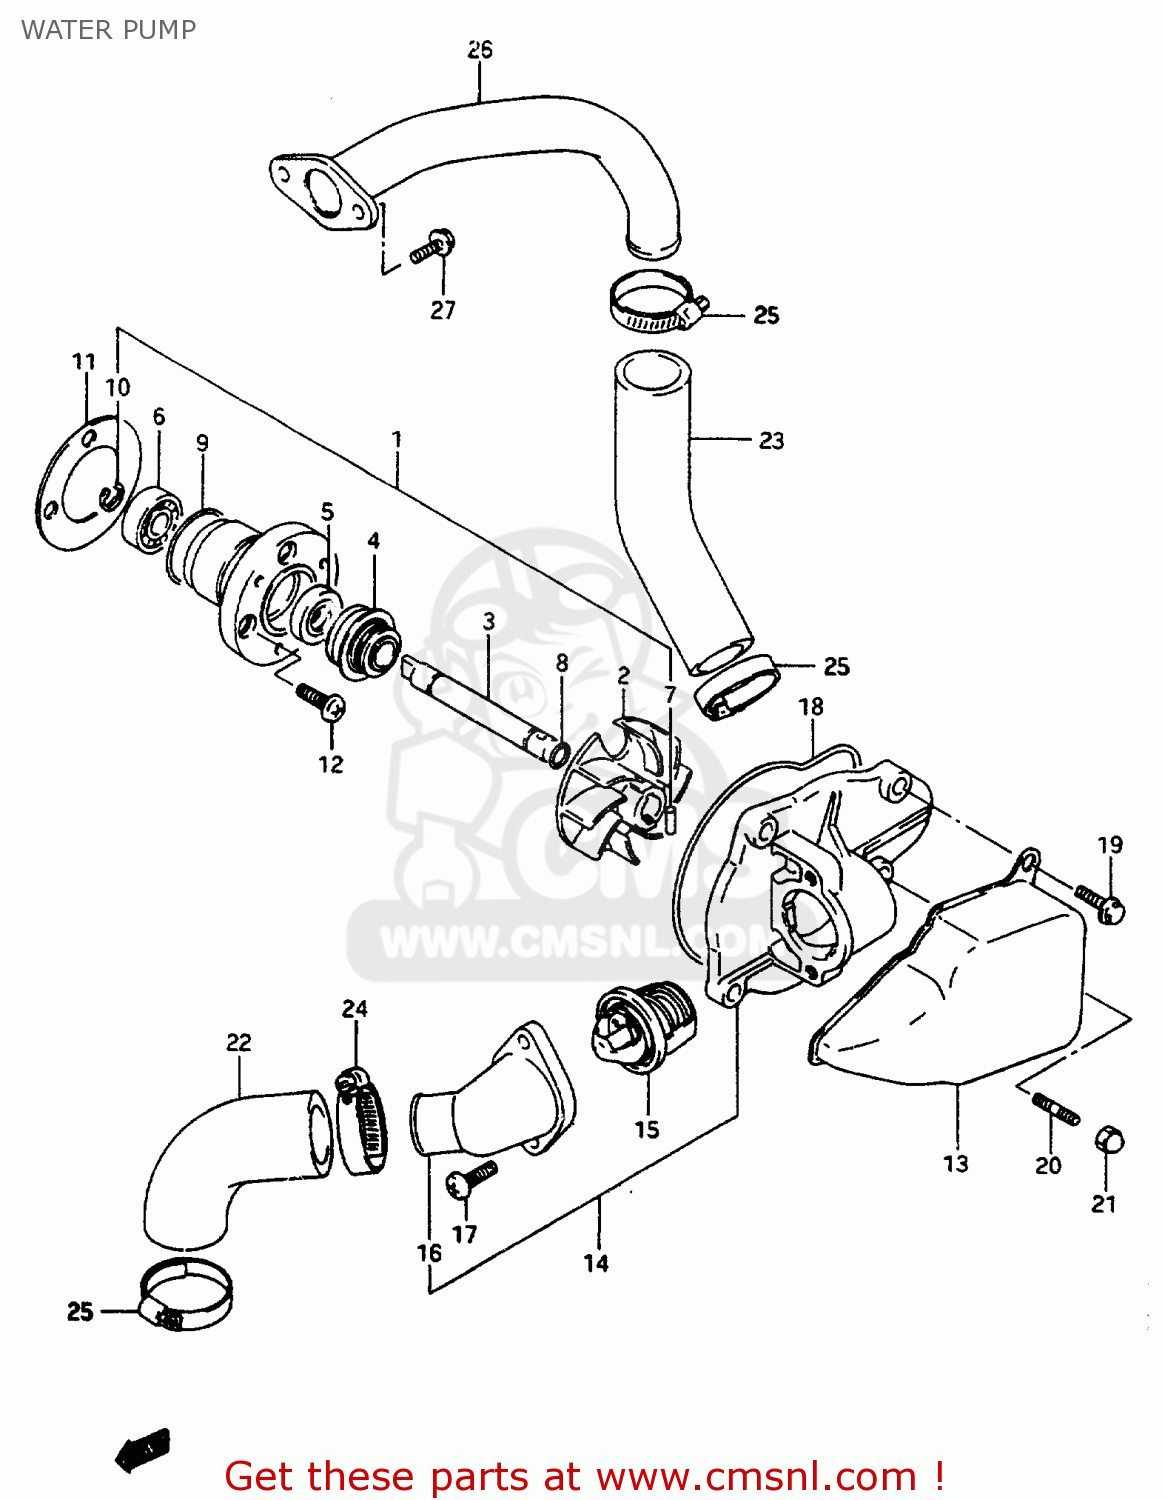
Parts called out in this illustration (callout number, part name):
1	PUMP ASSEMBLY,WATER
2	IMPELLER
3	SHAFT
4	SEAL,MECHANICAL
5	OILSEAL
6	BEARING,10X26X8
7	PIN
8	O RING
9	O RING
10	E RING
11	GASKET,WATER PUMP (NAS)
12	SCREW
13	COVER,WATER PUMP
14	CASE ASSY,WATER PUMP
15	THERMOSTAT,WATER
16	CONNECTOR
17	SCREW
18	O RING,WATER PUMP CAP
19	BOLT
20	STUD
21	NUT
22	HOSE,WATER PUMP IN
23	HOSE,WATER PUMP OUTLET
24	CLAMP
25	CLAMP
26	PIPE,CYLINDER INLET
27	BOLT
